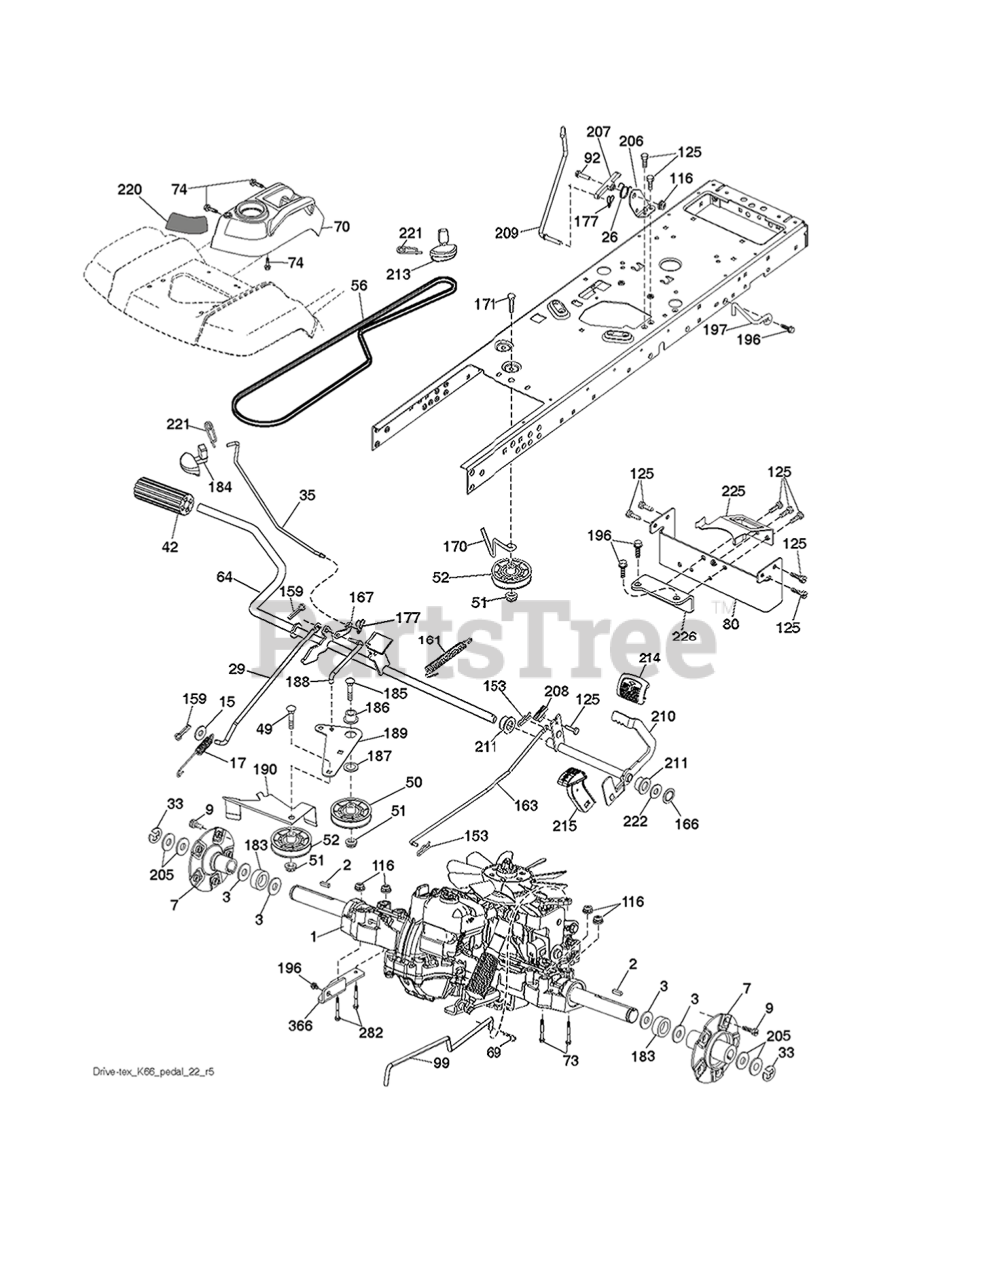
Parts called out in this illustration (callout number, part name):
1	TRANSAXLE.K66DL.PEDAL.CONTROL
1	ABSORBER
2	KEY, 1/4 SQ X 1 1/4
7	HUB.PNT.GT.PM.1IN.AXLE.E-DIP
15	WASHER PLAIN WASHER 3/8 X 0.08
17	SPRING.BRAKE.K46
26	SPRING.RETURN.CRUISE
29	ROD.BRAKE.K66
33	E RING HYT
42	PAD, FOOT PEDAL
50	IDLER.FLAT.910.OFFSET
51	NUT.HEX.FLANGE.3/8-16.LOCKNUT
52	IDLER.V-GROOVE.910.OFFSET
64	SHAFT.ASM.PEDAL.BRK.CNTR
69	HAIRPIN.SOFT.ZINC.059X1.125
70	CONSOLE.ASM.RH.GT.FC.HUSQ
80	STRAP.PNT.TORQUE.K66.EDIP
99	ROD.BYPASS.K66
125	BOLT.HEX.HD.WASHER.5/16-18X.75
153	RETAINER M
161	SPRING, RETURN LT
163	ROD.PEDAL.CONTROL
166	NUT.PUSH.625
167	SERVICE KIT LATCH LATCH.BRAKE.
170	KEEPER.V-IDLER.CENTER.
177	PIN COTTER;LOCKING;BOWTIE;1IN
183	SPACER.SPLIT;1.00.ID 1.75"
184	HANDLE.PARKING.BRAKE.H (BLK)
186	SPACER.RETAINER
188	LINK.CLUTCH.GROUND DRIVE.LONG
189	SERVICE KIT BELLCRANK
190	KEEPER.BELLCRANK.DRIVE
196	SCREW 3/8-16X1
206	BRACKET.MOUNT.CRUISE.LATCH
210	ROCKER.ASM.PEDAL.CONTR
211	BEARING.NYLON
213	KNOB.CONTROL.CRUSIE.HU
214	PEDAL.FORWARD.PAD.TEX
215	PEDAL.COVER.REVERSE.CRD.X428BK
220	REFLECTOR.RH.TEX GT
221	RETAINER.SPRING.CLIP.H
222	WASHER 21/32 X 1-1/4 X 10 GA.
225	KEEPER.BELT.TRANSAXLE.K66
226	BRACKET.MOUNT.TORQUE.K66.TG
282	BOLT HEX FLGHD 5/16-18X3 GR. 5
